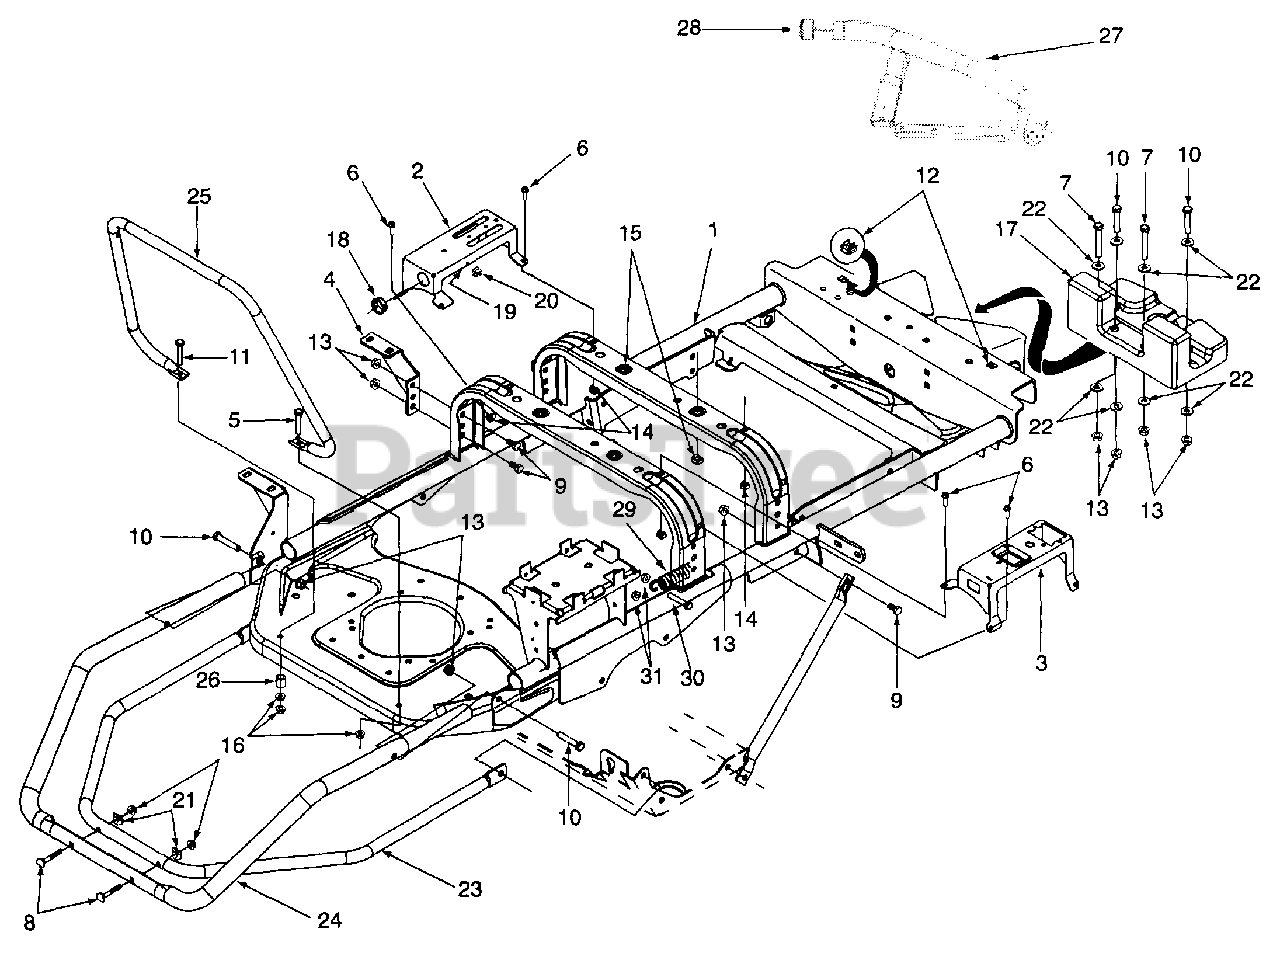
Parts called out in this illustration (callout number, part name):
6	Screw, Hex Wash. Hd. Tapp 1/4-20 x .625
7	Screw, Hex Cap 3/8-16 x 2.5 GR5
8	Screw, Curved Hd. Carriage 5/16-18 x 2.0
9	Screw, Hex Cap 3/8-16 x 3/4 GR5
10	Screw, Hex Cap 3/8-16 x 2.0 GR5
11	Screw, Hex Cap 5/16-18 x 1.75 GR5
12	Nut, Retainer, 3/8-16
13	Nut, Hex Flange Lock, 3/8-16
14	Nut, Retainer, 1/4-20
15	Nut, Retainer, 3/8-16
16	Nut, Hex Flange Lock, 5/16-18 GR5
19	Rivet, Pop, .125
20	Clip, Spring
21	Washer, Saddle
22	Washer, Flat, .406 x .875 x .105
29	Spring
30	Screw 1/4-20 x 1.0
31	Nut 1/4-20
